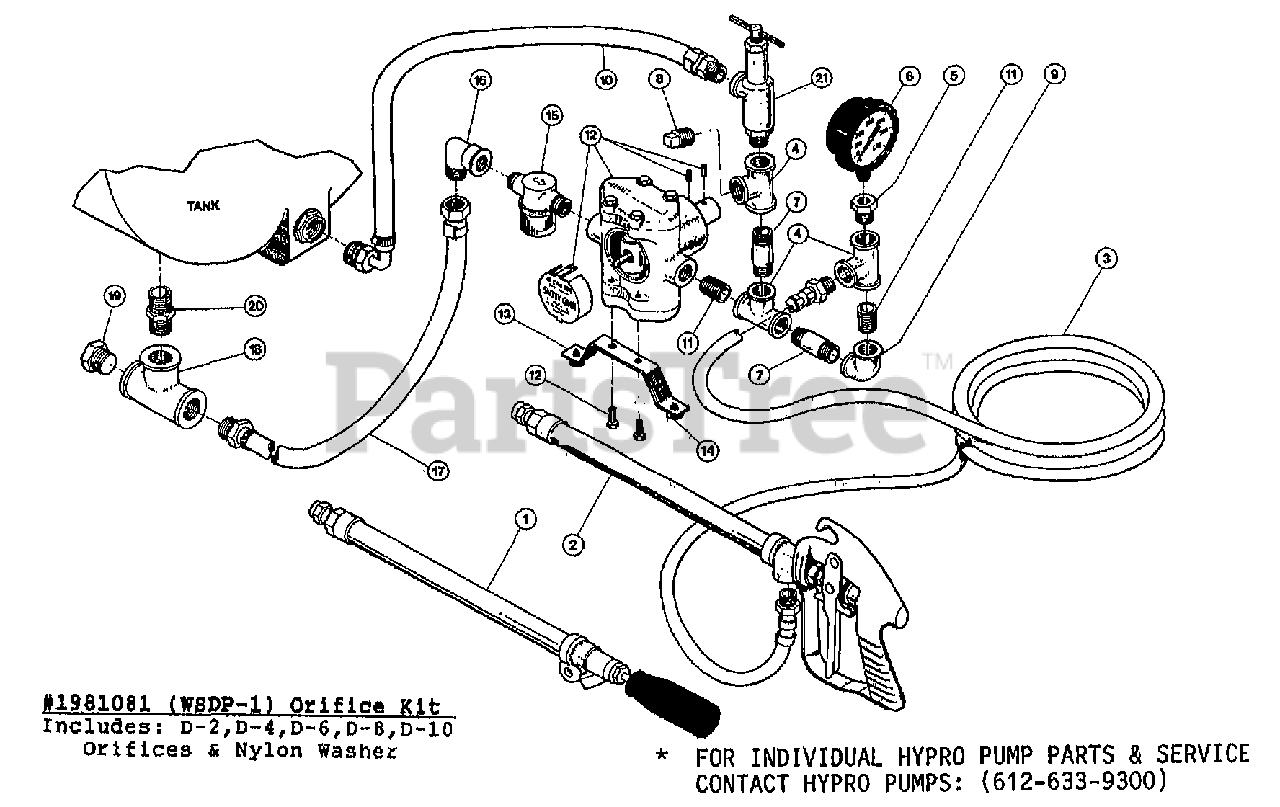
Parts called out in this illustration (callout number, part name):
1	GUN-TWIST SPRAY W143BR1/2
2	GRIP-PISTOL W43H6BR SPRAY GUN
3	HOSE-3/8 X 25' W2075660
4	TEE-1/2" PIPE W20983014
5	PIPE-BUSHING REDUCING
6	GAUGE-GLYCERINE PRESS WLFS220
7	NIPPLE-PIPE 50X2 GALVANIZED
8	PLUG-PIPE .50" W20984014
9	ELBOW-PIPE .50" W20986014
10	HOSE-RETURN LINE W2075603
11	NIPPLE-1/2" CLOSE W20981014
12	PUMP-TWIN PISTON
13	ARM-TRQ 25G SPRAY W28200028
14	BUMPER-RUBBER TORQUE ARM
15	STRAINER W33500079
16	ELBOW-1/2" STREET WSE12
17	HOSE-17" SUCTION W2075661
18	TEE-3/4 PIPE NYL WTT34
19	PLUG-3/4" PLASTIC WF3400
20	NIPPLE-3/4 CLOSE WM1400
21	VALVE PRESS.
